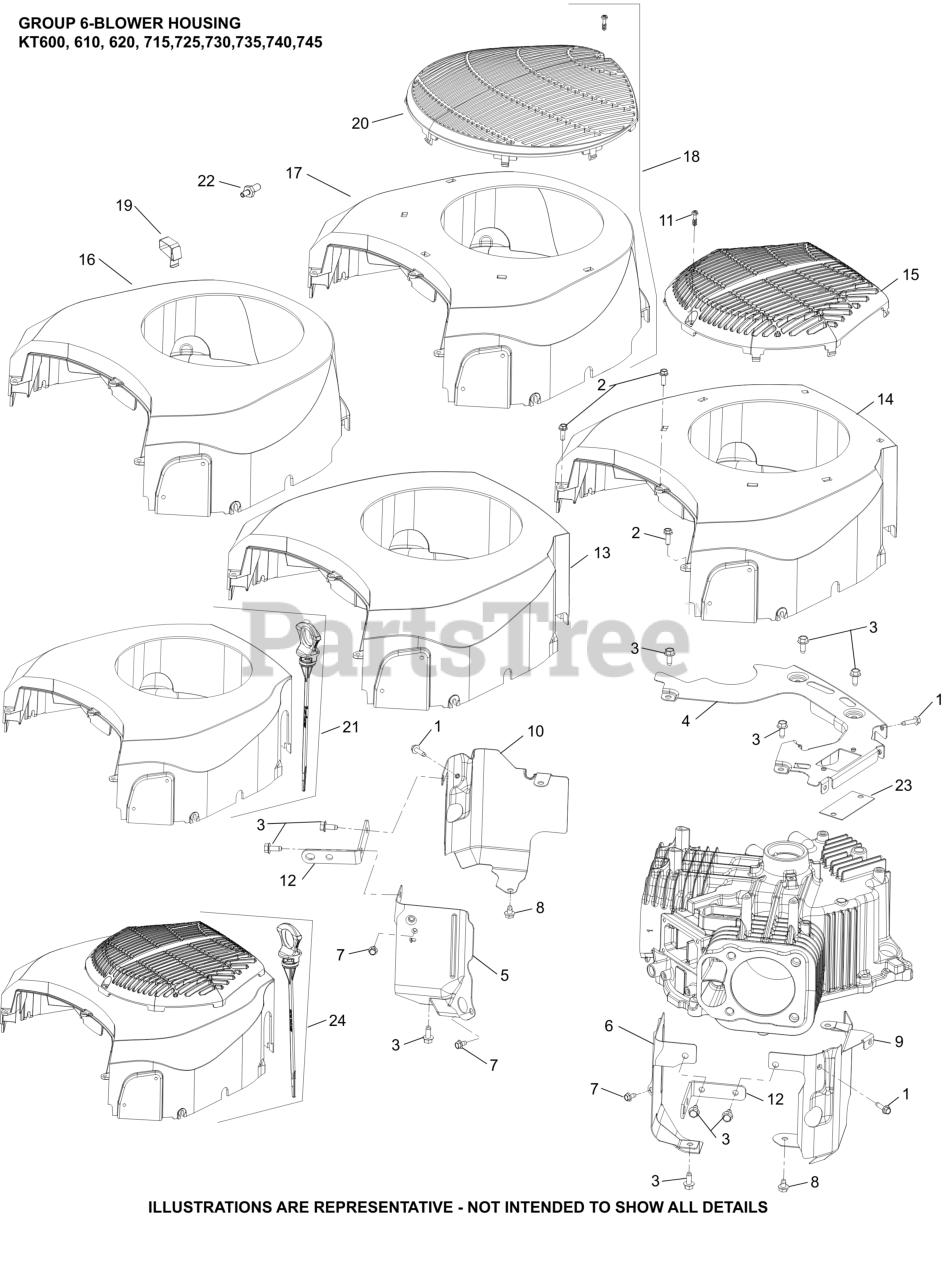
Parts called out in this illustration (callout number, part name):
1	SCREW, THD FRM-USE 25 086 473-S
2	SCREW, HI-LOW
3	SCREW, THREAD FORMING
4	PLATE, BACKING
5	BAFFLE, VALLEY #1
7	SCREW, THREAD FORMING
9	BAFFLE, LEFT BARREL
10	BAFFLE, RIGHT BARREL
11	SCREW, M5-2.42 (PT) THREAD
12	STRAP, LIFTING
15	GUARD, FIXED
19	CLIP, BLOWER HOUSING
NI	KIT, BLOWER HOUSING
NI	BAFFLE, VALLEY #2
